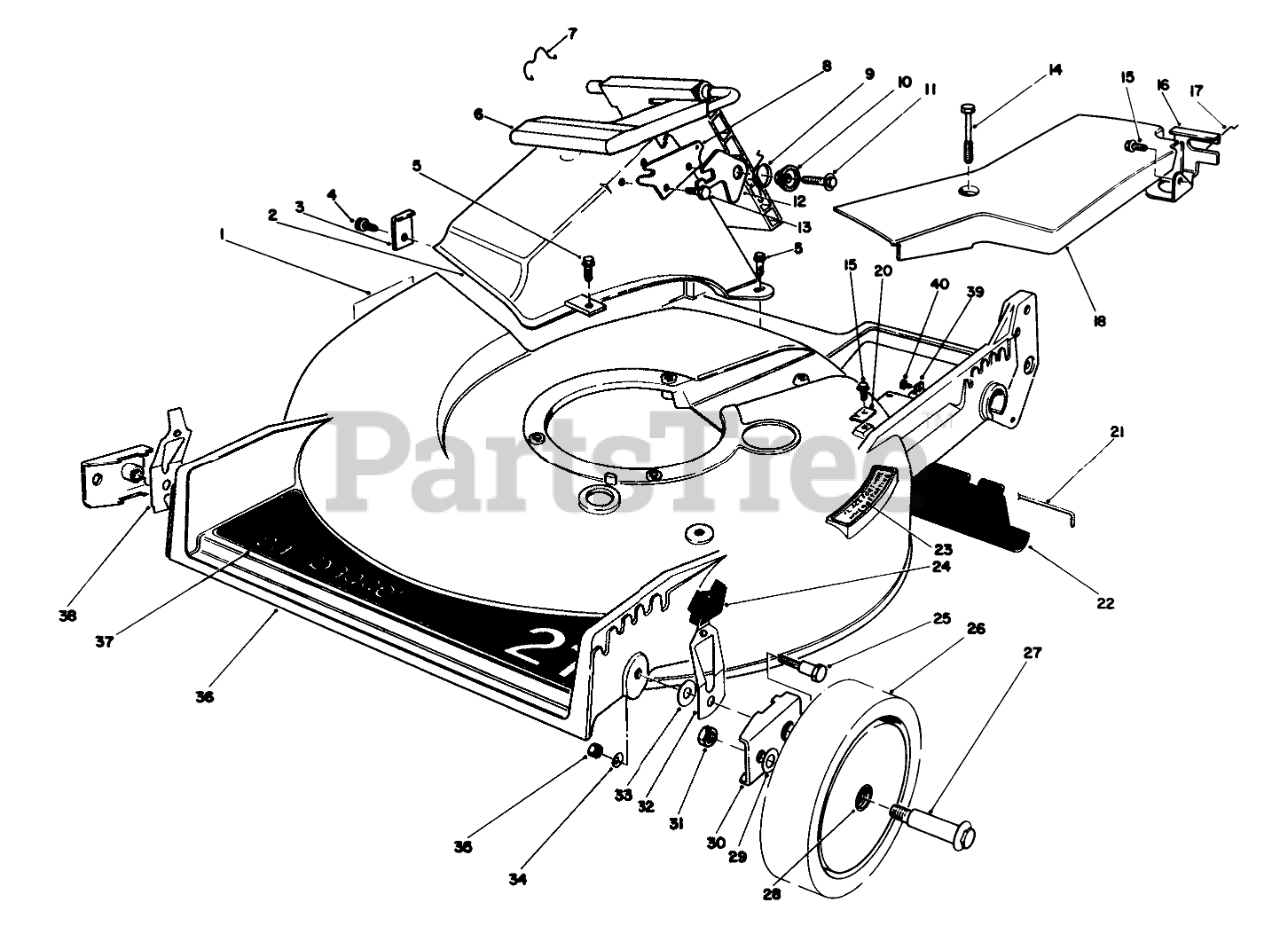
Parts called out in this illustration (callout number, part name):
1	DECAL-DANGER
2	Tunnel Discharge
3	TUNNEL CLIP
4	SCREW
5	SCREW-HWH
6	Discharge Door Assembly
7	DOOR RET SPRING
8	DOOR LATCH PLATE
9	Spring-Torsion
10	DOOR SPACER
11	SCREW-HWH
12	SAFETY LATCH
13	SCREW-PLASTITE
14	SCREW-HHFTF
15	SCREW-HWHTF
16	Bracket-Traction Adj.
17	RETAINER-CABLE
18	Cover-Belt
20	CLAMP-CABLE
21	ROD-SHIELD
22	SHIELD-TRAILING
23	STEP PAD DECAL
24	KNOB-ARM
25	PIVOT SCREW
26	Wheel & Tire Assembly (Incl. Ref. #28)
27	BOLT-WHEEL
28	BUSHING
29	WASHER
30	HP PIVOT ARM ASM
31	Nut
32	L. HP SPRING ARM ASM
33	WASHER-PIVOT
34	WASHER-BELLEVILLE
35	NUT-LOCK, NI
36	Housing (Incl. Ref. #1, 5 & 23)
37	DECK DECAL
38	R HP SPRING ARM ASM
39	CLAMP-CABLE
40	SCREW
